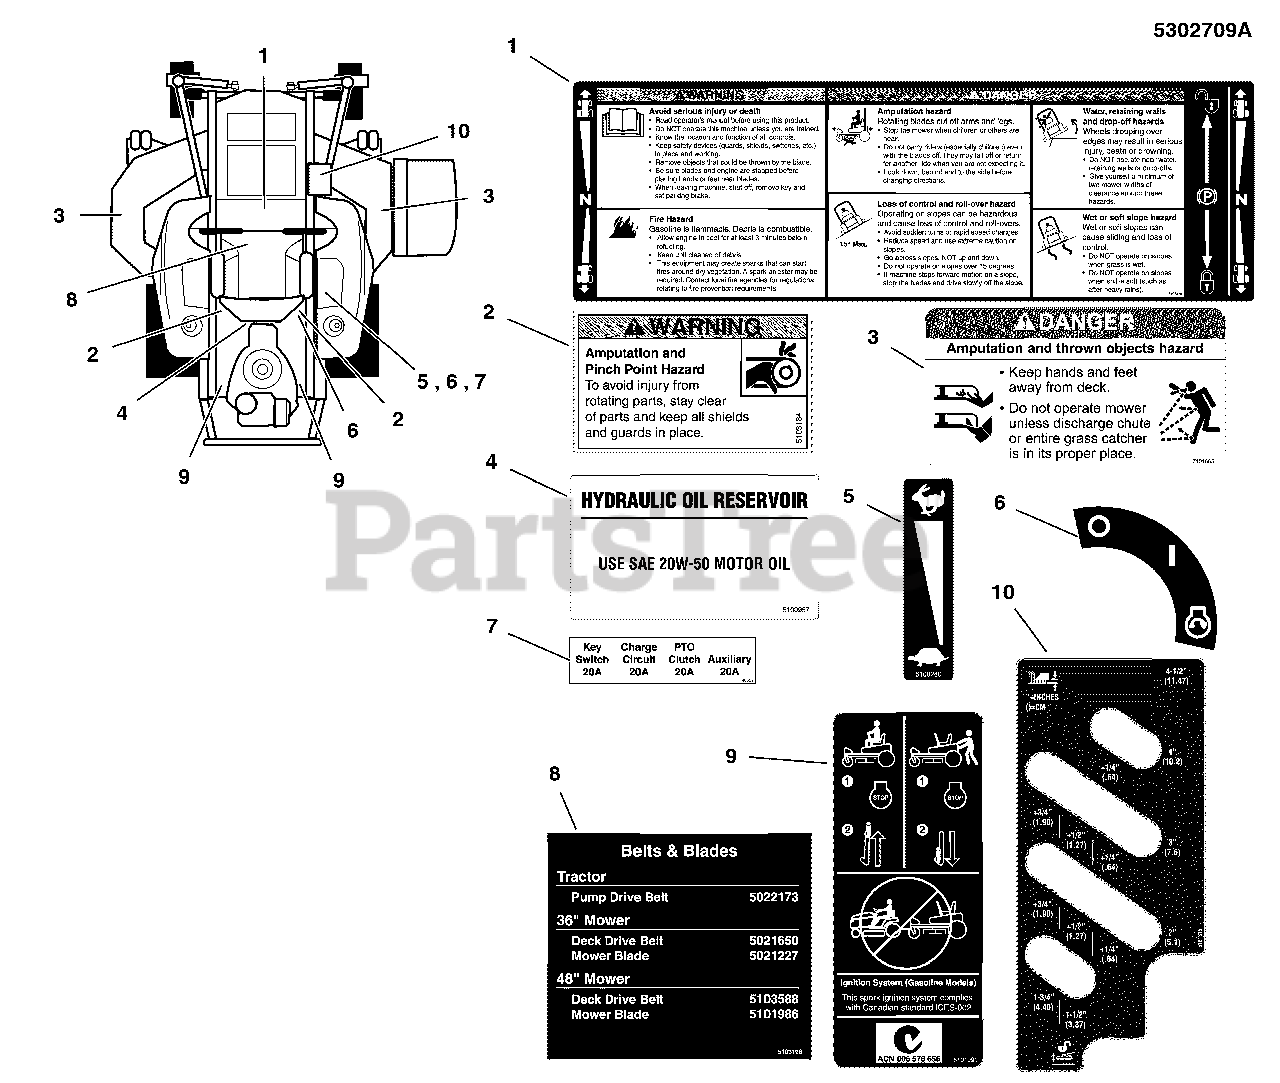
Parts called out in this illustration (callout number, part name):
1	DECAL, MAIN SAFETY
2	DECAL, WARNING, HAND IN BELT, ENG ONLY
3	DECAL, DANGER DO NOT OPERATE W/O DEFLECT
4	DECAL, HYDRAULIC OIL, SAE 20W50
5	DECAL, THROTTLE CONTROL
6	DECAL, IGNITION SWITCH
7	DECAL, FUSE LOCATION
8	DECAL, BELT & BLADE, S50X iCD
9	DECAL, TRANSAXLE RELEASE
10	DECAL, CUT HEIGHT, S50X
